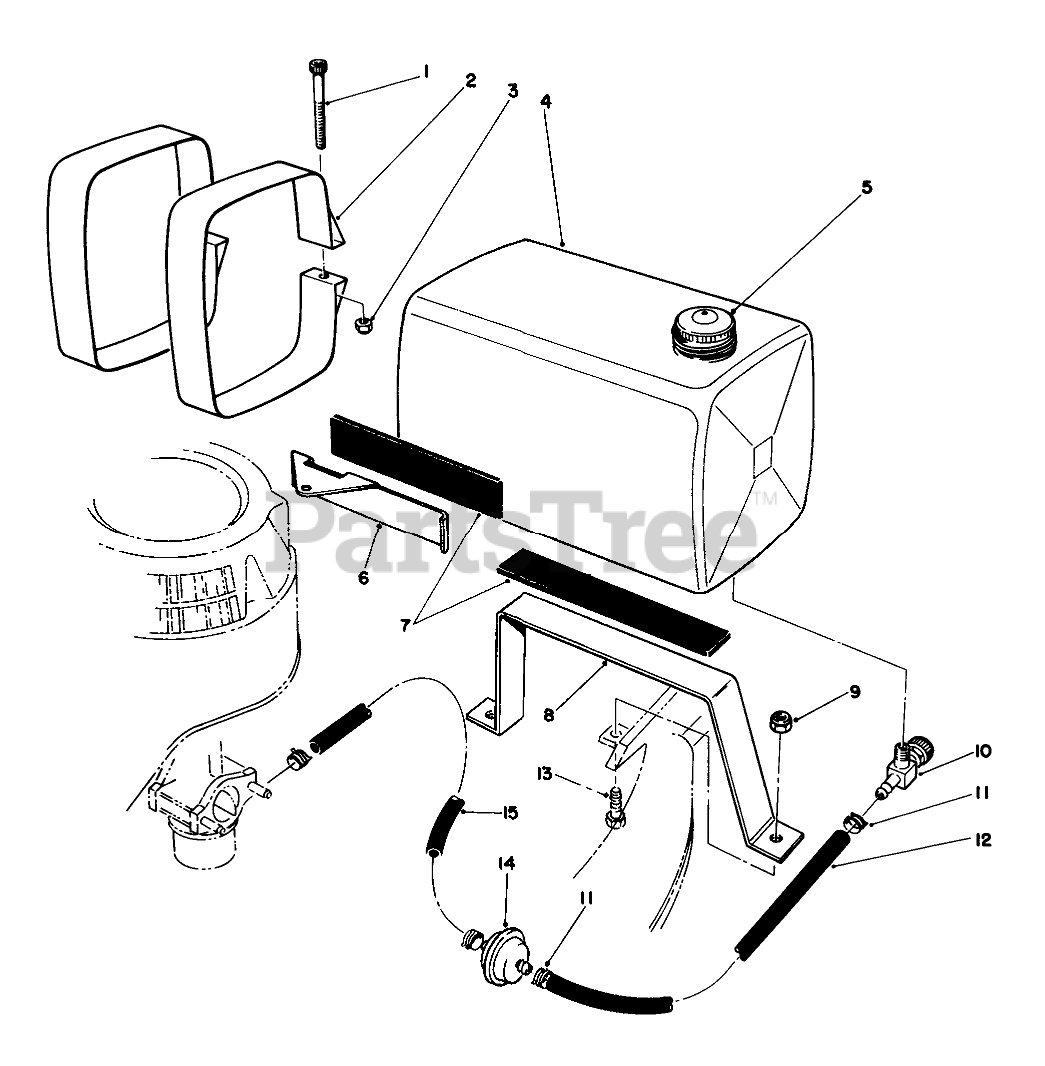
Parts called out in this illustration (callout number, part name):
1	SCREW-HSH
2	TANK STRAP WA
3	NUT-HEX
4	Tank-Gas (Incl. Ref. #5)
5	GAS CAP
6	FRT TANK MOUNT
7	ISOLATOR PAD
8	TANK BOTTOM MOUNT
9	NUT-LOCK, NI
10	.125 ID SHUTOFF VALVE
11	CLAMP-FUEL LINE
12	LINE-GAS
13	SCREW-HH
14	FILTER-FUEL
15	HOSE-FUEL
